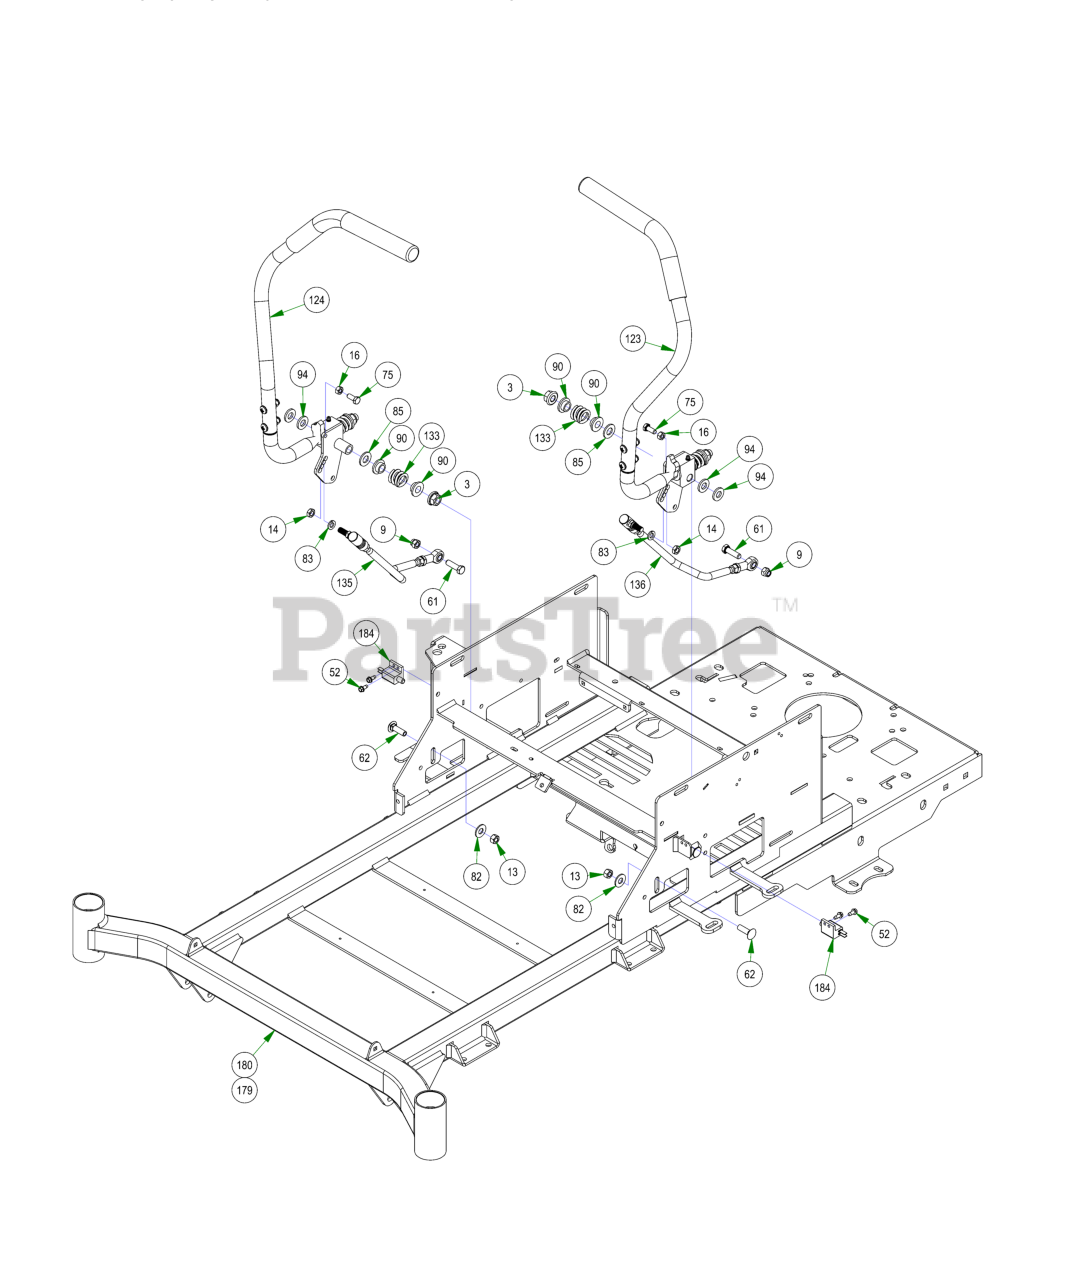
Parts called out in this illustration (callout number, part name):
3	1/2-13 HEX FLANGE AUTO OVAL LOCKNUT (GR.F) ZINC/WAX
9	3/8-16 NYLON INSERT LOCKNUT ZINC
13	3/8-16 HEX NUT ZINC
14	3/8-24 HEX NUT ZINC YELLOW
16	5/16-18 HEX NUT ZINC
52	12-24 X 1/2 HEX WASHER UNLSOT F TCS ZINC
61	3/8-16 X 1-1/4 HEX CAP SCREW (GR.5) ZINC
62	3/8-16 X 1-1/4 CARRIAGE BOLT ZINC
75	5/16-18 X 3/4 HEX CAP SCREW (GR.5) ZINC
82	3/8 FLAT WASHER USS (1" OD) ZINC
83	3/8 SPLIT LOCKWASHER ZINC
85	1/2 SAE FLAT WASHER (1-1/16" OD) GR.8 ZINC YELLOW
90	.525 ID SHOULDER WASHER NYLON
94	.505 ID X 1.000 OD X .125 THICK FLAT WASHER NYLON
123	2017 MZ Magnum LH Steering Arm
124	2017 MZ Magnum RH Steering Arm
133	Drive Lever Spring
135	Push Rod-Right
136	Push Rod-Left
179	2022 MZ/ZT 54"-60" Frame
180	2022 MZ/ZT 42"-48" Frame
184	Safety Switch
